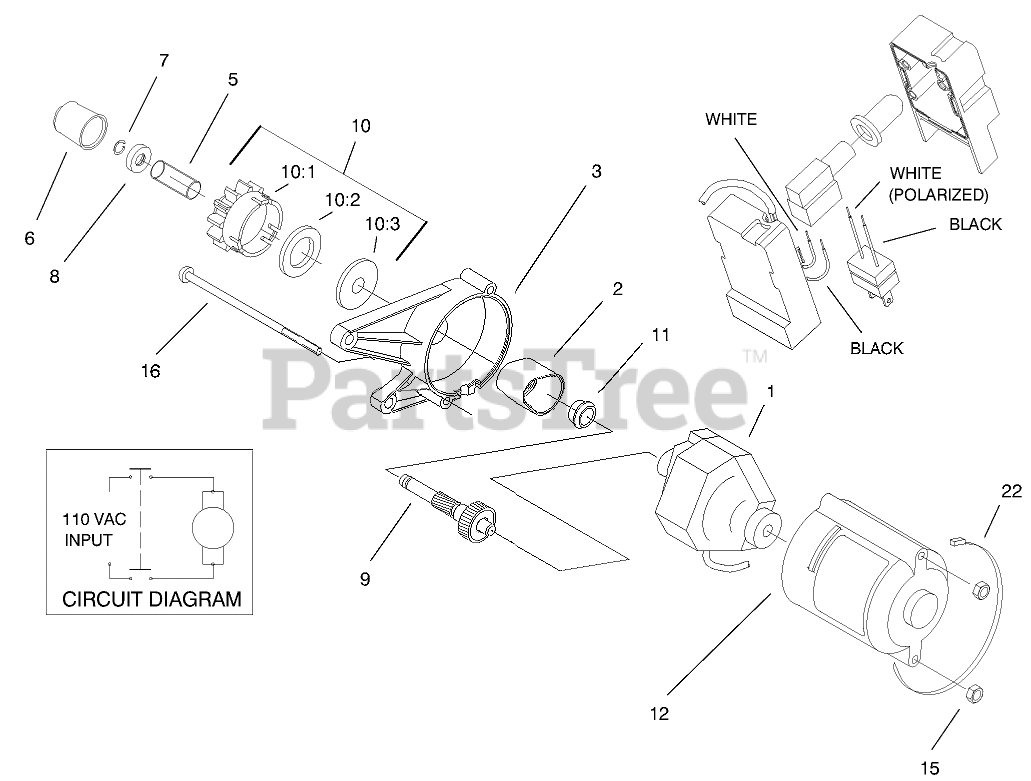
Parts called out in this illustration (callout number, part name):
1	Starter Motor Assembly (only on: 38405)
2	Gear Cover (only on: 38405)
3	Housing Upper Starter (only on: 38405)
5	Spring (only on: 38405)
6	Cap Pinion (only on: 38405)
7	Lock Ring (only on: 38405)
8	Pinion Stop (only on: 38405)
9	Shaft/Gear ASM-Service (only on: 38405)
10	Pinion ASM (R & S)(only on: 38405)
10:1	Nut (only on: 38405)
10:2	Pinion (only on: 38405)
10:3	Ring-Rubber (only on: 38405)
11	Bushing (only on: 38405)
12	Housing Lower Starter (only on: 38405)
15	Nut-Lock Ni (only on: 38405)
16	Screw-Mach (only on: 38405)
22	TIE-CABLE
